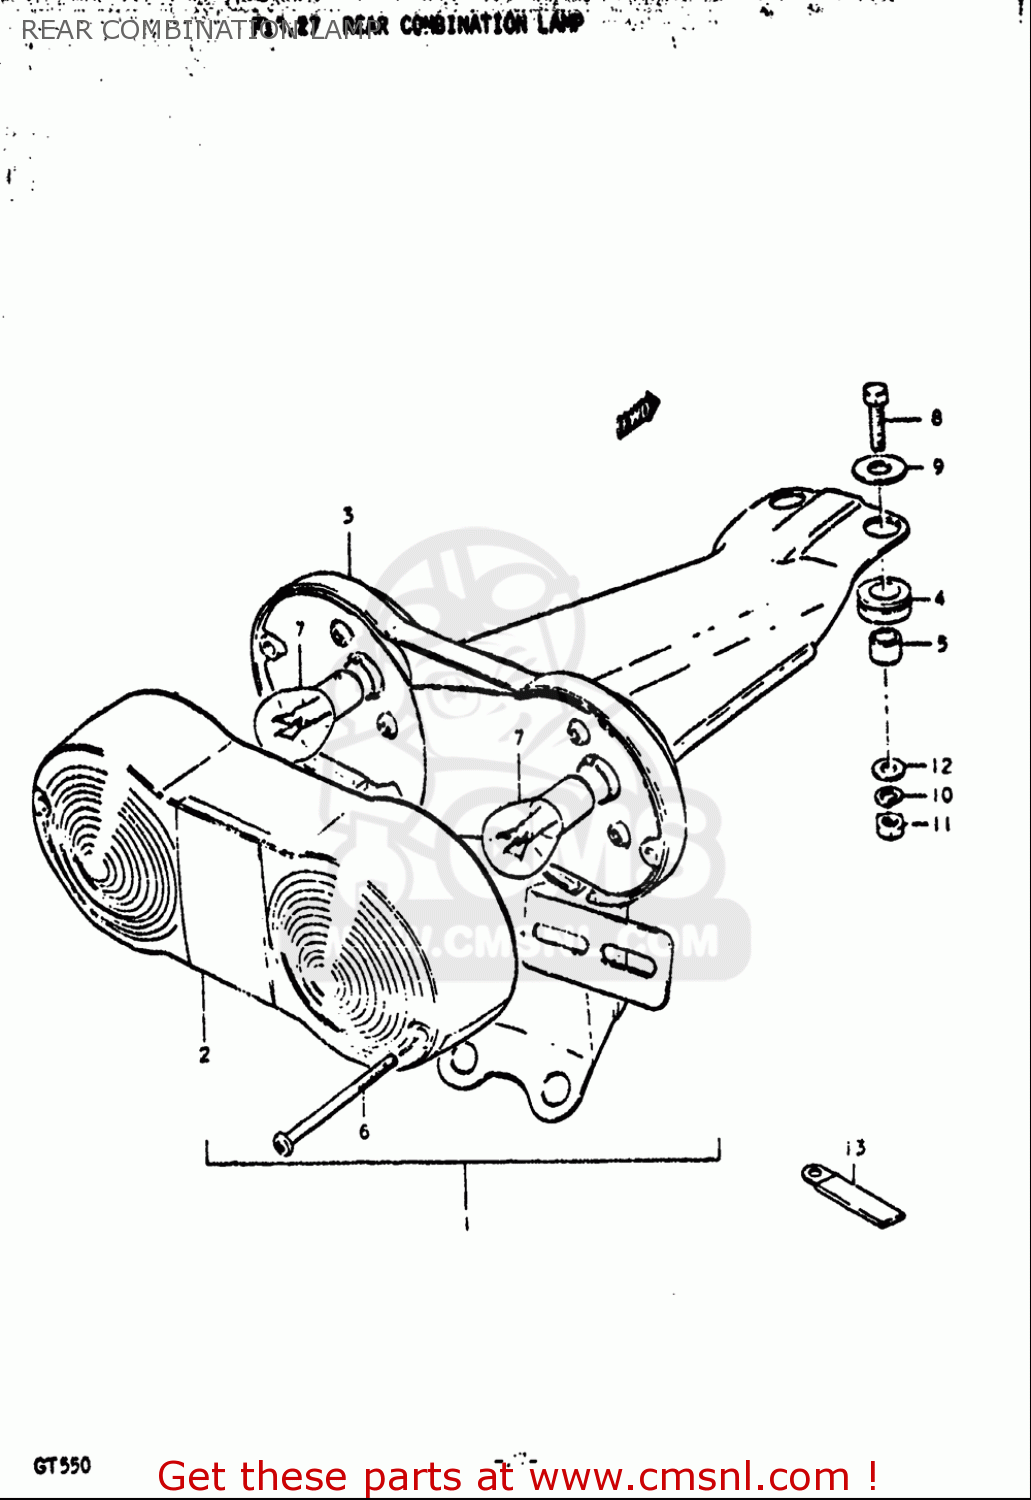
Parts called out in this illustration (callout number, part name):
2	LENS,REAR COMBINATION LAMP
4	CUSHION
5	SPACER
6	SCREW
7	BULB(12V23W)
8	BOLT
9	WASHER(6.5X20X1.6)
10	WASHER,LOCK
11	NUT
12	WASHER
13	CLAMP
